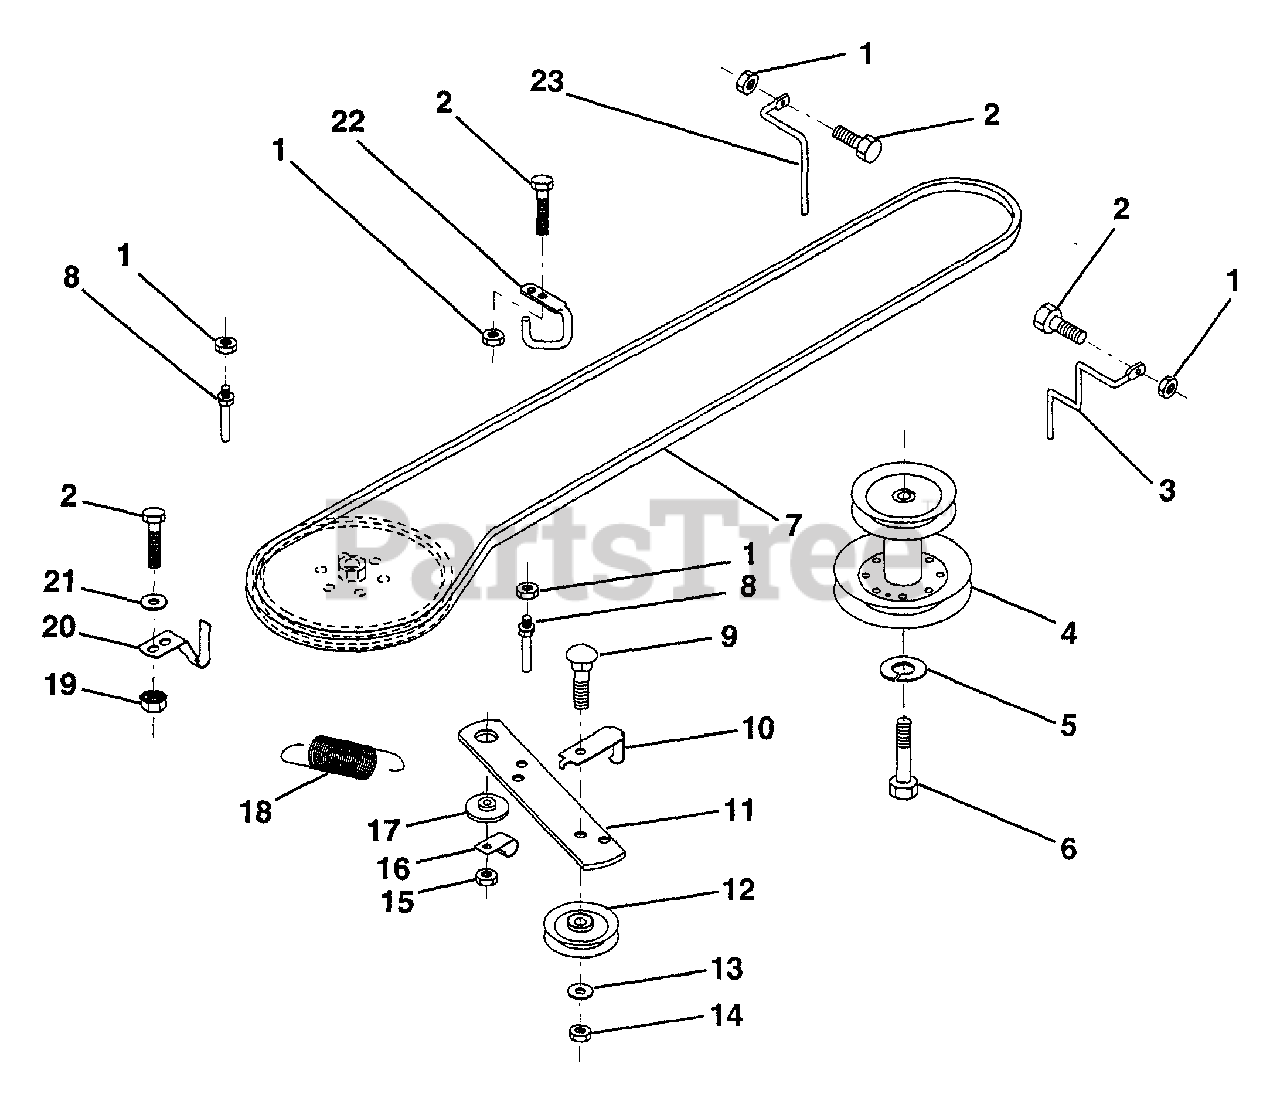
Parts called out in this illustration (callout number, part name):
1	Nut, Crownlock 5/16-18
2	Bolt, Hex Hd. 5/16-18 UNC x 3/4
3	Keeper, Mower Drive Belt, R.H.
4	Pulley, Engine
5	Washer, Lock 7/16
6	Bolt, Hex, Fin. 7/16-20
7	Traction, V-Belt, Drive
8	Keeper, T/A, Ground Drive Belt
9	Bolt, Carriage 3/8-16 UNC x 1-1/2
10	Keeper, Ground Drive, Belt, Idler
11	Clutch Arm, Ground Drive
12	Idler, Flat
13	Washer 13/32 x 13/16 x 16 Ga.
14	Nut, Centerlock 3/8-16 UNC
15	Nut, Crownlock 3/8-16 UNC
16	Clip, Insulated
17	Spacer, Retainer
18	Spring Extension
19	Nut, Hex, Keps 5/16-18 UNC
20	Keeper, T/A, Ground Drive Belt
21	Washer 11/32 x 5/8 x 16 Gauge
22	Keeper, Frame, Ground Drive Belt
23	Keeper, Mower Drive Belt, L.H.
